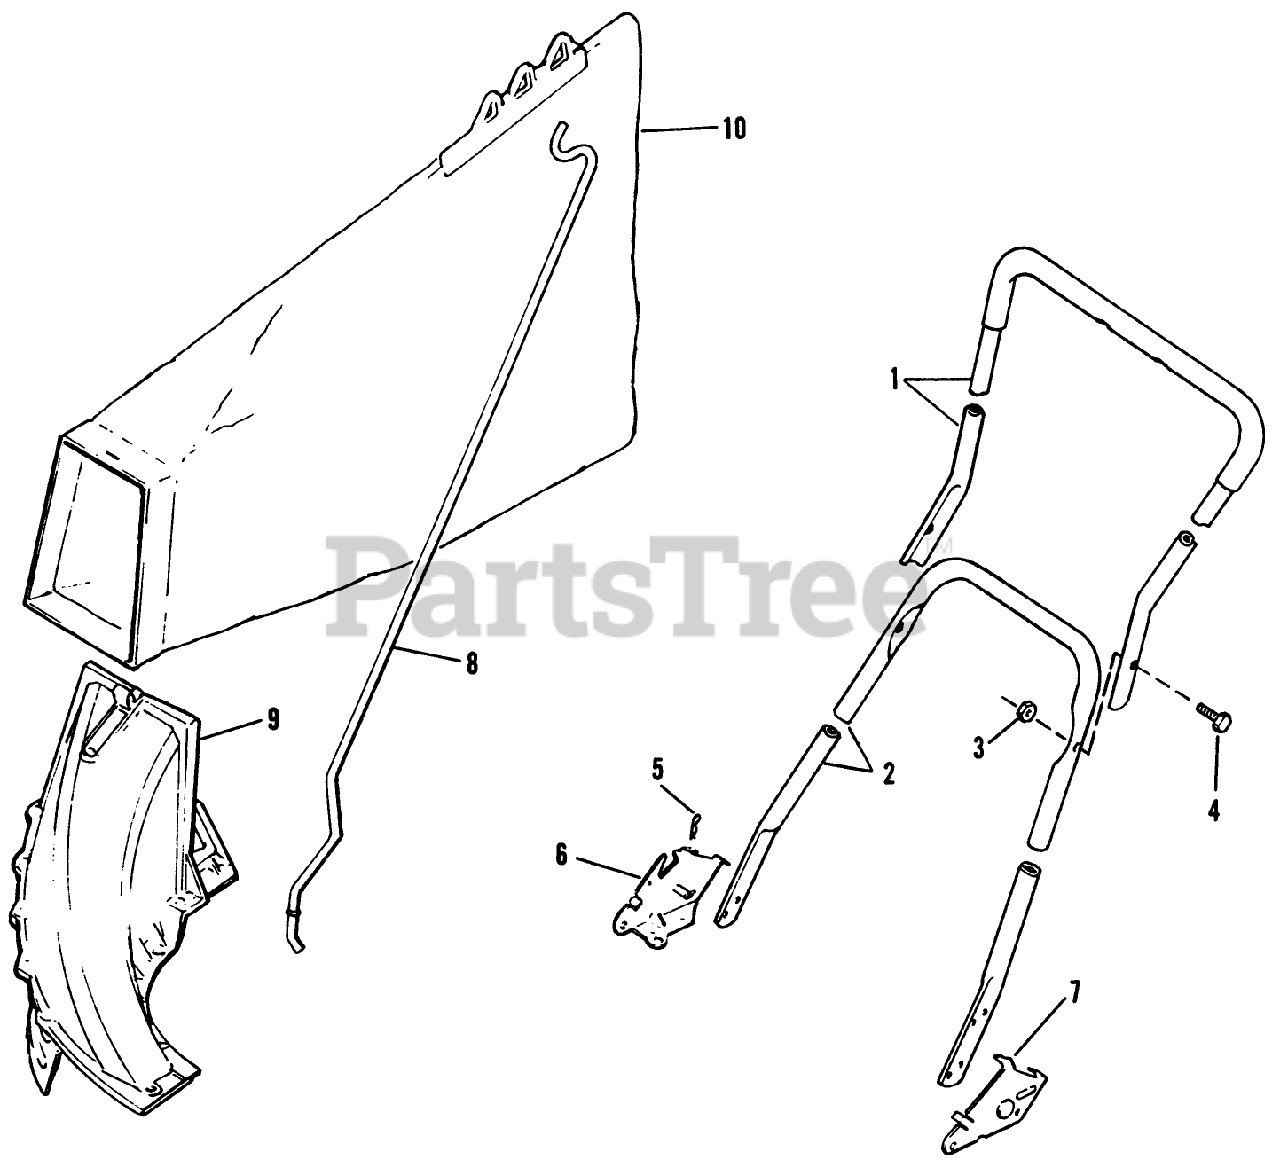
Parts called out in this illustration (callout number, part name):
2	HANDLE SECTION *B
3	LOCKNUT E
5	HAIR PIN
8	ROD GRASSBAG
